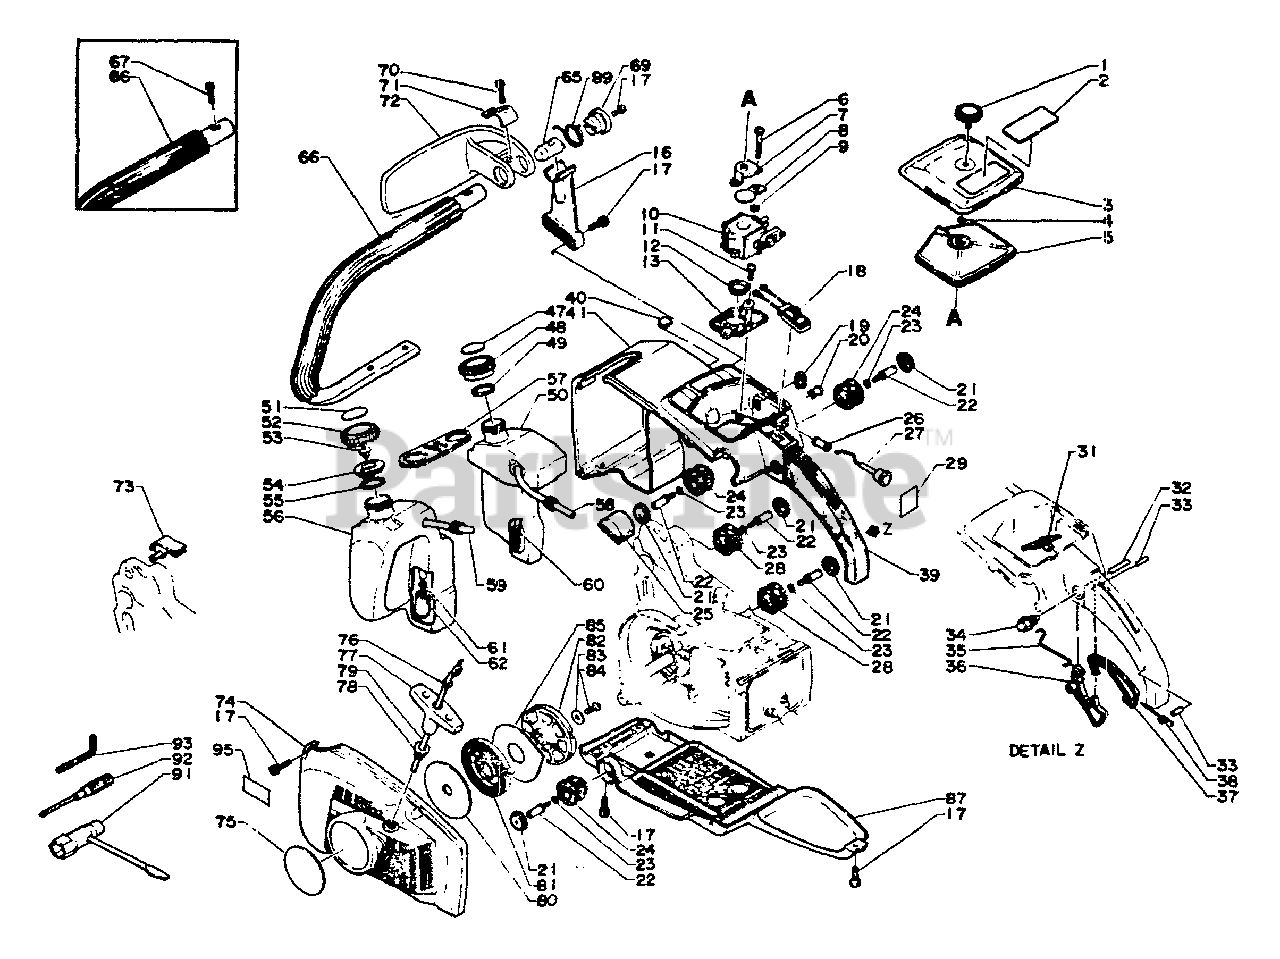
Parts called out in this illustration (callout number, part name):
1	THUMBSCREW
2	LABEL - MODEL
3	COVER, AIR FILTER
4	O-RING - 3
5	FILTER, AIR
6	SCREW - 5X40
7	BRACKET, AIR CLEANER
8	SHUTTER, CHOKE
9	WASHER - 5
10	CARBURETOR WA-96
11	SCREW - 4X12
12	SEAL
13	ADAPTOR, CARBURETOR
16	BRACKET, HANDLE - UPPER
17	SCREW - 5X20
18	IGNITION SWITCH ASSY
20	GROMMET
21	CAP, CUSHION
23	LOCKWASHER - 5
25	COVER, CUSHION
26	GROMMET
27	ROD, CHOKE
29	LABEL - CHOKE
32	PIN - SPRING -- 5X25
33	PIN - SPRING -- 4X13
34	LATCH, THROTTLE
35	ROD, THROTTLE
36	TRIGGER, THROTTLE
37	LOCKOUT, THROTTLE
38	SPRING, LOCKOUT LEVER
39	GRIP, HANDLE - REAR
41	HANDLE - REAR
47	LABEL - CHAIN OIL
48	CAP, OIL TANK
49	GASKET, CAP
50	TANK, OIL
51	LABEL - FUEL MIX
52	CAP
54	HOLDER, VENT
55	O-RING - 22
56	TANK, FUEL
57	CONNECTOR
58	OIL PIPE KIT
59	FUEL PIPE KIT
60	FILTER, OIL
61	WASHER - 5
62	FILTER, FUEL
66	HANDLE - FRONT
67	SCREW - 5X25
69	PLATE, HAND GUARD
70	SCREW - 5X30
71	STOPPER
72	GUARD
73	COVER
74	CASE, STARTER
75	LABEL - ECHO
76	RING, RETAINING
77	GRIP, STARTER
78	GUIDE, ROPE
79	ROPE, STARTER - 3.5X850
80	PLATE, STARTER
81	SPRING, REWIND
82	REEL, ROPE
83	WASHER - 5
84	SCREW - 5X10
85	PLATE, STARTER
87	SUPPORT
91	T-WRENCH - 10X19mm
92	SCREWDRIVER
93	HEX KEY - 4mm
95	LABEL - NOISE
